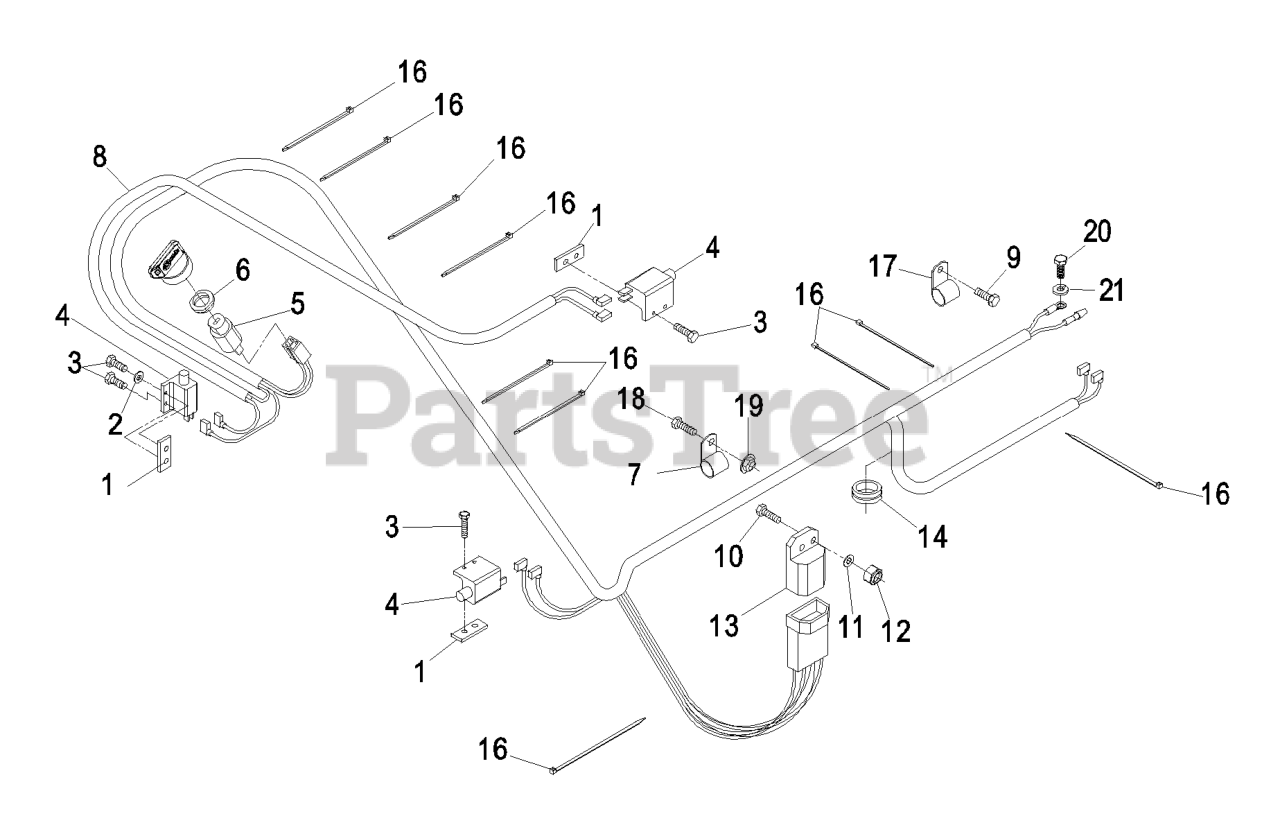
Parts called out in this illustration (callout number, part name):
1	PLATE-TAPPED
2	WASHER-FLAT
3	SCREW-PPH
4	SWITCH-OPEN, NORMALLY
5	SWITCH & KEY (INCLUDES NU
6	NUT-SWITCH, IGNITION
7	CLIP-LOOM
8	HARNESS-WIRING
9	SCREW-HH
10	SCREW-HH
11	WASHER-FLAT
12	NUT-LOCK, NI
13	MODULE-INTERLOCK
14	GROMMET
16	TIE-CABLE
17	CLIP-LOOM
18	SCREW-HH
20	SCREW-HH
21	WASHER-LOCK
